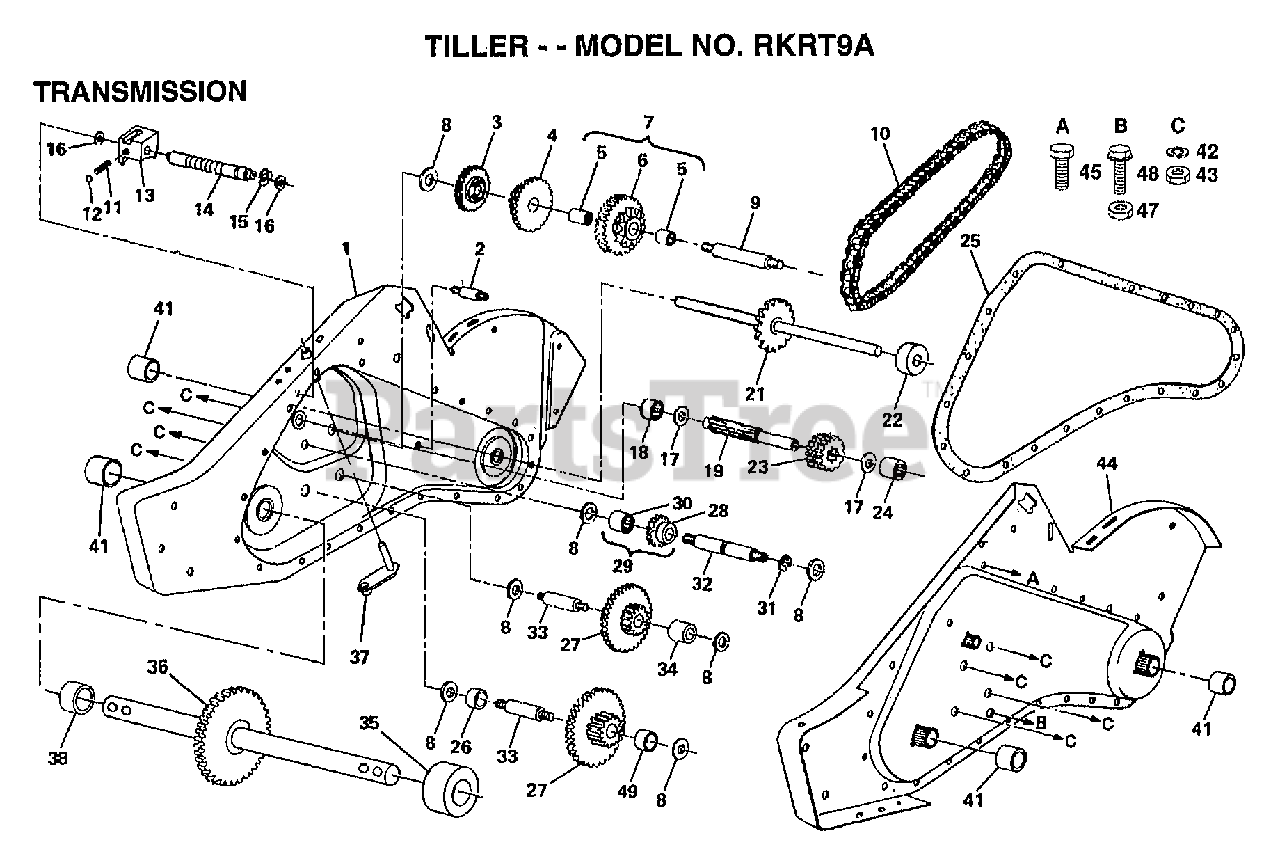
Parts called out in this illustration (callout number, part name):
2	BOLT TI
3	REVERSE GEAR TI
4	CLUSTER GEAR TI
5	"CRT, BEARING"
7	SPROCKET ASSY TI
8	WASHER
9	REDUCTION SHFT TI
10	CHAIN TI
11	SPRING-SHIFT CRT
13	SHIFT FORK TI
14	SHIFT SHAFT TI
15	KLIP RING
16	WASHER SEAL
17	"T, BEARING"
18	"TI, BEARING"
19	SHAFT INPUT
21	SHAFT TINE CRT
22	SPACER CRT
23	INPUT PINION TI
24	NEEDLE BRNG LT
25	GASKET.GEARCASE
26	SPACER CRT
27	GEAR CLUSTER CRT
28	REVERSE GEAR TI
29	GEAR ASSY TI
30	NEEDLE BEARING TI
31	KLIP RING
32	REVERSE SHAFT TI
33	SHAFT CRT
34	SPACER CRT
35	SPACER CRT
36	SHAFT ASSY CRT
37	BRACKET ASM SHIFT
38	SPACER CRT
41	SEAL ASM-OIL
42	LOCKWASHER
43	NUT.ASF.HEX.7/16
44	"GEARCASE ASSY,LH"
45	SCREW 5/16-18X5/8
47	NUT.HEX.5/16-18
48	BOLT TI
49	SPACER CRT
